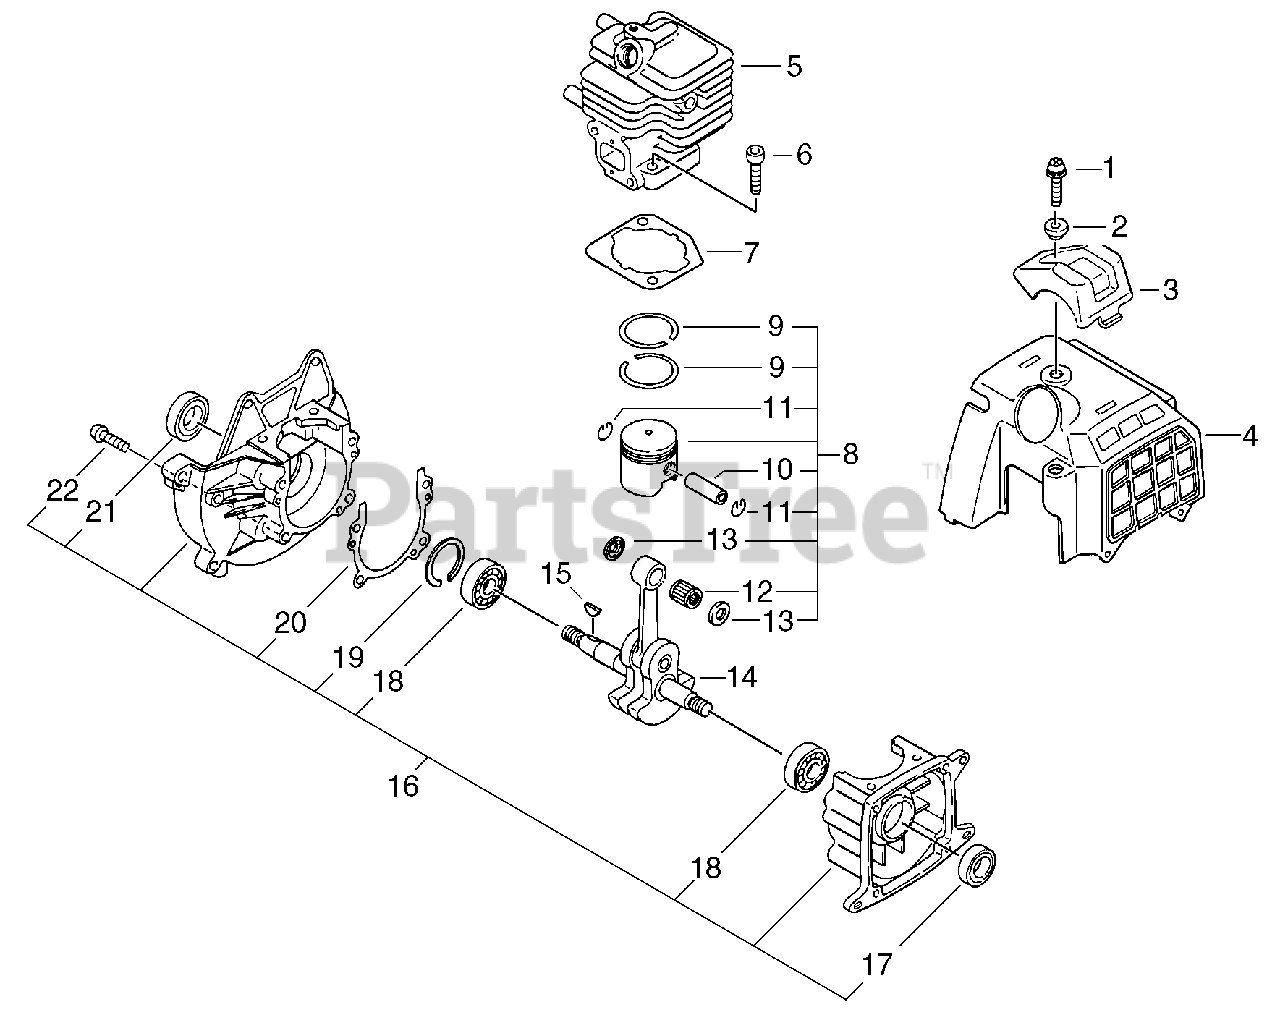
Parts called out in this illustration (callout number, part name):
1	BOLT - 5X20 -- FLANGE
2	COLLAR - 5
3	GUARD - TOP
4	COVER, ENGINE
5	CYLINDER
6	SCREW - 5X22
7	GASKET, CYLINDER
8	PISTON KIT
9	RING, PISTON
10	PIN, PISTON
11	RING, RETAINING
12	BEARING, NEEDLE - 8
13	SPACER, PISTON
14	CRANKSHAFT ASSY
16	CRANKCASE KIT
17	SEAL, OIL
18	BEARING, BALL - 6001C3
19	RING, RETAINING - 28
20	GASKET, CRANKCASE
21	SEAL, OIL - 12
22	SCREW - 5X25
